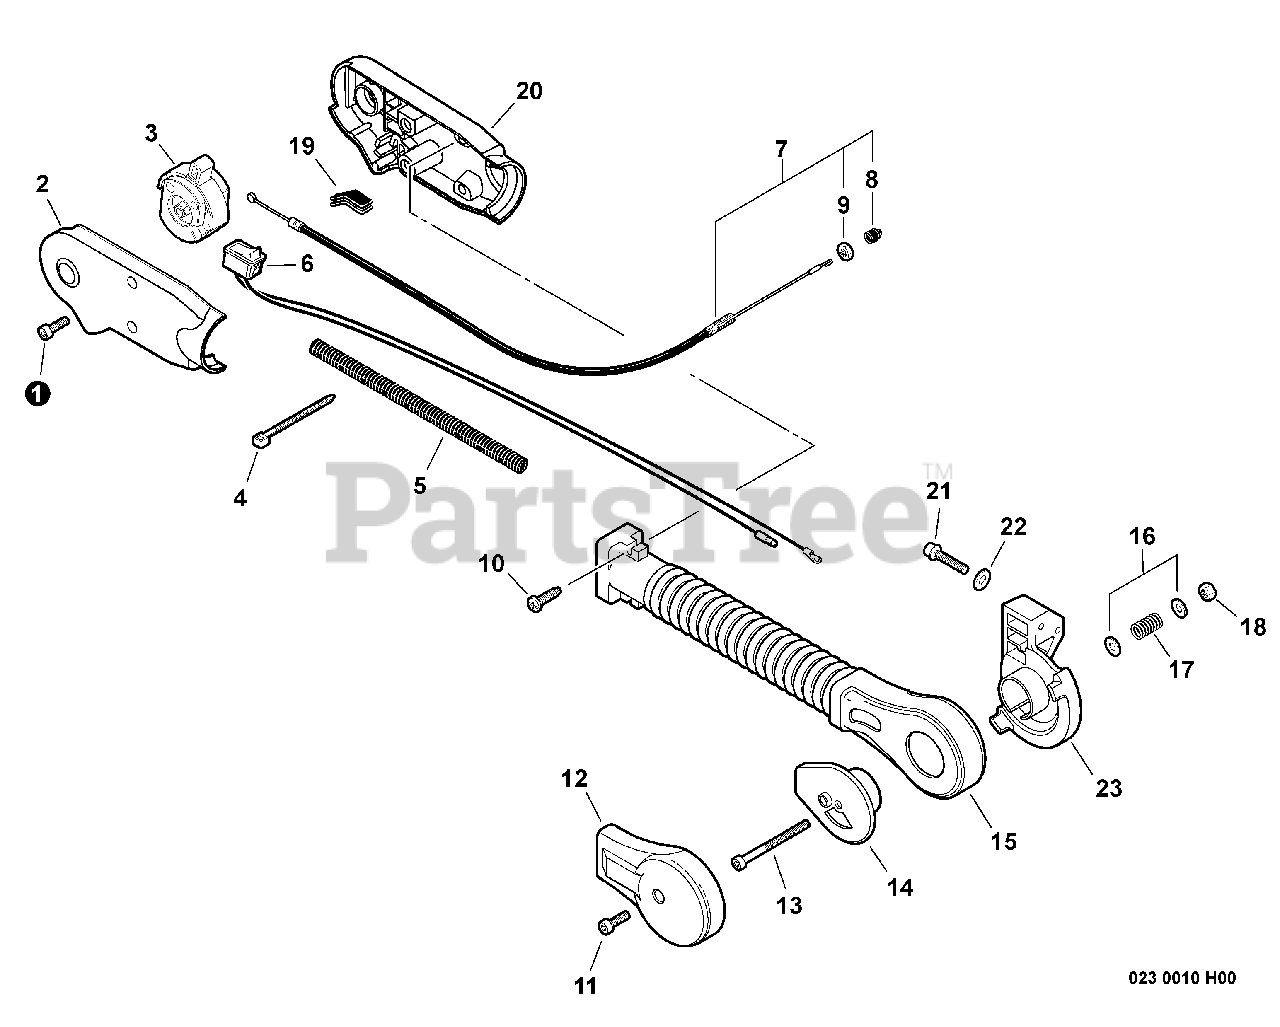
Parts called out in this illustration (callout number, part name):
1	BOLT 5×14
2	GRIP, LEFT THROTTLE
3	THROTTLE CONTROL ASSY
4	STRAP, TIE
5	TUBE, FLEXIBLE Ø7×160
6	SWITCH, ON-OFF
7	CABLE ASSY, THROTTLE L= 648.6
8	CAP, DUST
9	NUT, HEX M6
11	BOLT 5×14
12	COVER, BRACKET
13	SCREW M5×80
14	BRACKET, ARM - OUTER
15	ARM, THROTTLE CONTROL
16	WASHER 5.5×18×1
17	SPRING, COMPRESSION Ø9.53×24.13
18	NUT, LOCK M5
19	GROMMET
20	GRIP, RIGHT THROTTLE
21	BOLT, TAPPING 5×25
22	WASHER 5.5×16×2T
23	BRACKET, ARM - INNER
